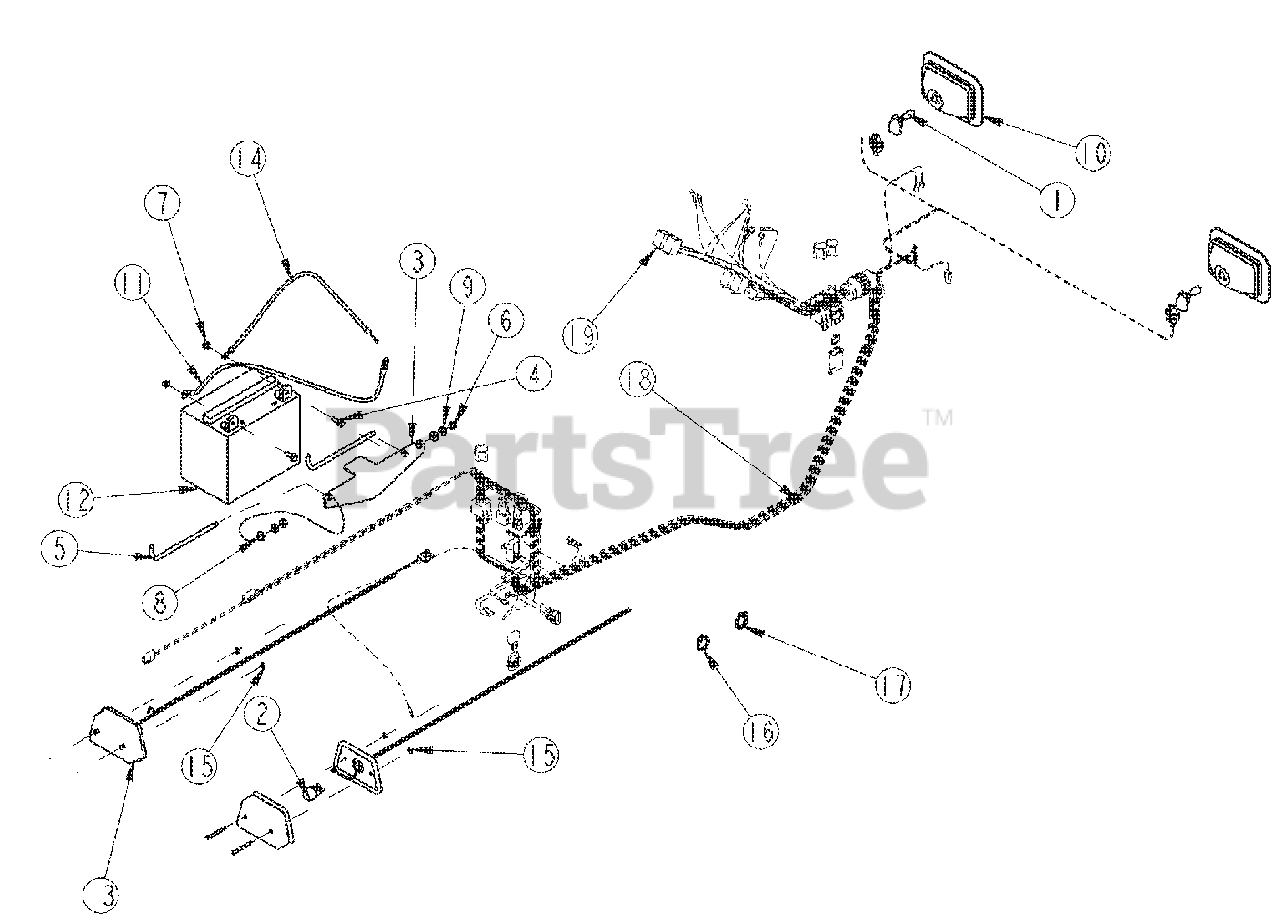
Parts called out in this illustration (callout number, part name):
1	HEADLIGHT BULB 37.5 WATT 894
2	TAILLIGHT BULB 1157 1157
3	HOLDOWN, BATTERY ST
4	HFSS 1/4-20X3/4 GR5
5	SP HOOK 5/16-18X9X3 THREAD
6	NUT, HEX 5/16-18 PLT
7	NUT HEX FLNG T-LOCK 1/4-20 YLW
8	WASHER, FLAT 5/16 SAE
9	WASHER, LOCK 5/16
10	HEADLIGHT W/TRAP LENS 37.5WATT
11	BATTERY CABLE POSITIVE 15 INCH
12	BATTERY BUY LOCALLY BCI Group U1/U1R, Min. 300CA
13	TAIL LIGHT WITH STANDARD LEAD
14	20" 6GA NEGATIVE BLACK CABLE
15	PUSH RETAINERS 4 NON-THRD SHFT
16	CABLE TIE .19X14.25 3DIA 50LB
17	CABLE TIE 2 DIA MIN - BLK
18	WIRING HARNESS, MAIN ST
19	WIRE HARNESS INSTRUMENT PANEL
20	-209-150 RELAY BOSCH
